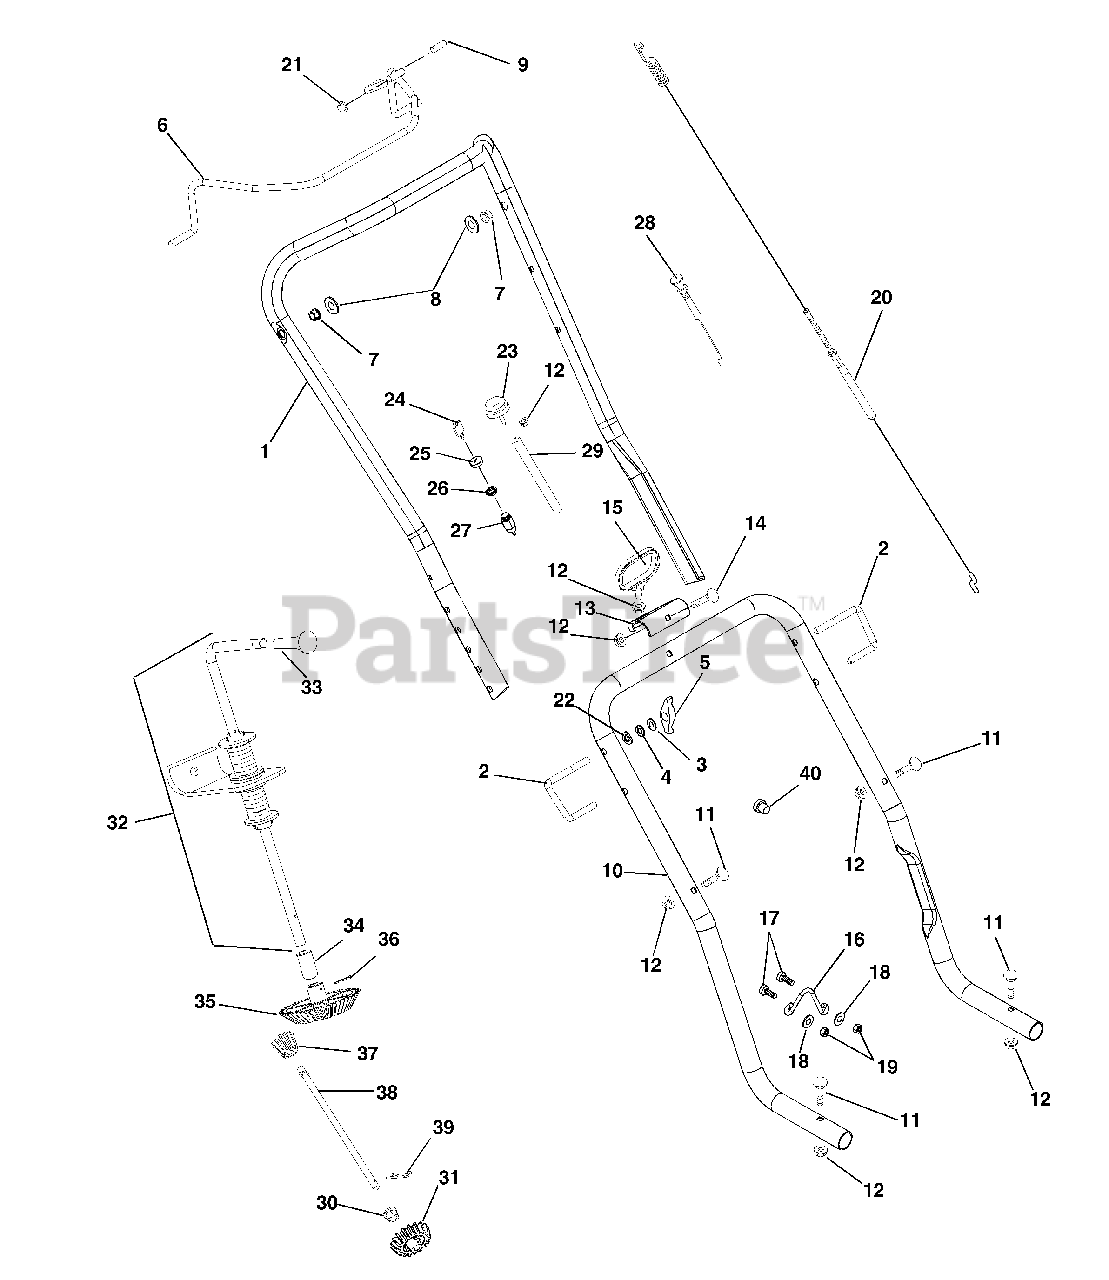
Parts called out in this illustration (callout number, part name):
1	HANDLEBAR, UPPER
2	J BOLT .31-18
3	WSHR-FL-STL .328X.875X.062YWZC
4	WSHR-LK .312X.097 HVY YWZC
5	KNOB - WING .312-18 UNC
6	BAIL SS LF
7	BSHG-FLG .325X.444X.440X.560
8	@WSHR-FL-STL.344X.688X.065YWZC
9	CAP, VINYL, .25 ID
10	HANDLEBAR, LOWER
11	BLT-RDHDSQNK .25-20X1.75 G5YZ
12	NUT-LK-FLG .250-20 PL BLK
13	BRKT-STARTER HANDLE
14	BLT-RDHDSQNK .25-20X1.50 PL BL
15	HANDLE, RECOIL START
16	GUIDE-ROPE
17	@SCR-MCH 10-24X.75 HWH YWZC
18	@WSHR-FL-STL.219X.50X.049 YWZC
19	@NUT-LK-NYL 10-24 W/INSRT YWZC
20	CABLE-CLUTCH CONTROL
21	PUSH NUT, .25
22	WASHER,SADDLE-.320 X.937 X.062
23	PRIMER ASSY
24	KEY -W/CAP
25	CAP - IGNITION SWITCH
26	NUT-PANEL .625-32 GRECO
27	SWITCH ASSEMBLY
28	CONTROL-CHOKE 5 HP
28	CONTROL-CHOKE 3 HP
29	LINE-PRIMER
30	BSHG-FLG .325X.444X.440X.560
31	PINION-DISCHARGE CHUTE 18T
32	CRANK-CHUTE ASSY
33	KNOB
34	BSHG-SLV .510X.753X2.00
35	GEAR-CRANK TRANSFER 48T
36	@PIN-CTR .16X1.25 EXTPRSQCT YZ
37	PINION-CRANK TRANSFER 12T
38	SHAFT CHUTE CRANK TRANSFER
39	PIN-HAIR INT .08X.38X1.42 YWZC
40	PLUG-HOLE .50 DIA
